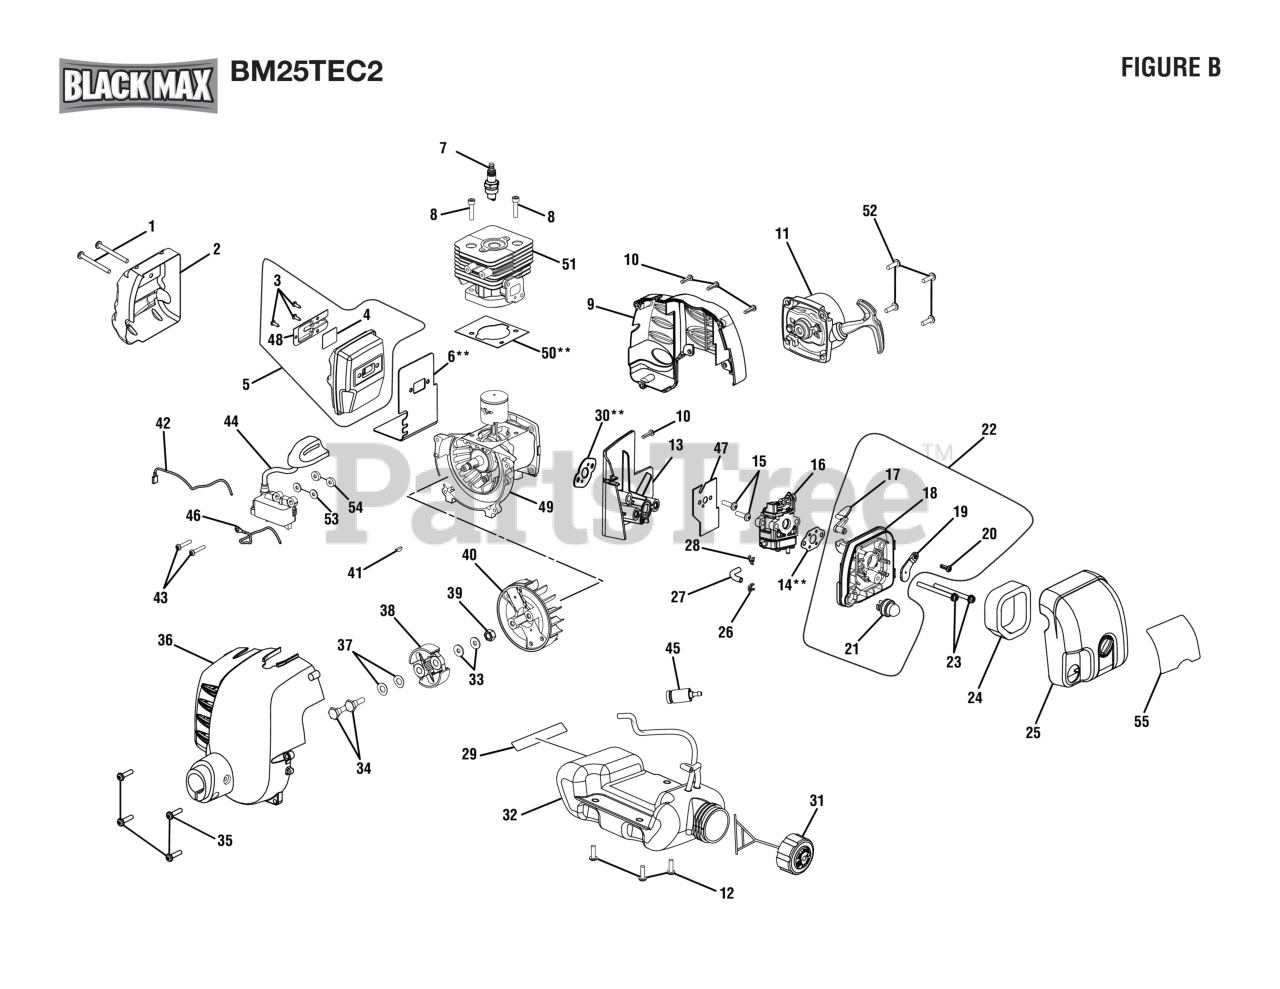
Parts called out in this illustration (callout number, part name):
1	Screw (M5 x 50 mm, Torx Slotted Recessed Pan Hd.)
2	HEAT SHIELD
3	Screw (6-20 x 1/4 in., T20 Torx Pan Hd. S.T.)
4	SCREEN
5	Muffler Assembly
6	Muffler Gasket
7	Spark Plug (Champion RCJ6Y)
8	Screw (M5 x 22 mm, T25 Torx Soc. Hd.)
9	ENGINE HOUSING, REAR
10	Screw (M4 x 18 mm, T20 Torx Pan Hd. S.T.)
11	Starter Recoil Assembly
12	Shoulder Screw w/Washer (M4 x 14 mm, T25 Torx Truss Hd.)
14	Carburetor Gasket
15	Screw (M5 x 30 mm, Torx T25)
16	CARBURETOR ASSEMBLY
17	Choke Lever
18	CARBURETOR PLATE
19	Screw (M4 x 12 mm, T20 Torx Pan Hd. S.T.)
20	Screw (M4 x 12 mm, Slotted Recessed Pan Hd.)
21	Primer Bulb Assembly
22	Filter Housing Assembly
23	Screw (M5 x 44 mm,T25 Torx Hd. Carburetor)
24	Air Filter (Element)
25	Air Box Cover Assembly
26	CLIP-HOSE (ID 4.9)
27	Fuel Line (45 mm)
28	Clip-hose (Id 4.9)
29	Warning Label (Combustion)
30	Heat Dam Insulator
31	Fuel Cap Assembly
32	Fuel Tank and Cap Assembly
33	Washer (ID6 x OD15 x 1.2t)
34	Clutch Shoulder Bolt (M6 x 22.5 mm, Hex Hd.)
35	Cap Screw w/Washer (M5 x 16 mm, T25 Torx Soc. Hd.)
36	Front Housing Assembly
37	Washer (Curved)
38	Clutch Assembly
39	Flange Nut (M8, Flywheel)
41	WOODRUFF KEY (10 mm X 3 mm)
42	Lead Wire Assembly, Black
43	Screw (M4 x 22 mm, T20 Torx Slotted Recessed Pan Hd.)
44	Coil Boot Assembly
45	Fuel Filter
46	Lead Wire Assembly, Red
47	Gasket
48	Trimmer Outlet
49	Crankcase Assembly.
50	Gasket
52	Cap Screw w/Washers (M5 x 16 mm, T25 Torx Soc. Hd.)
53	Flat Washer (OD10 x ID42 x 1t)
54	Phenolic Spacer (Ignition Module)
55	Start Instruction Label
